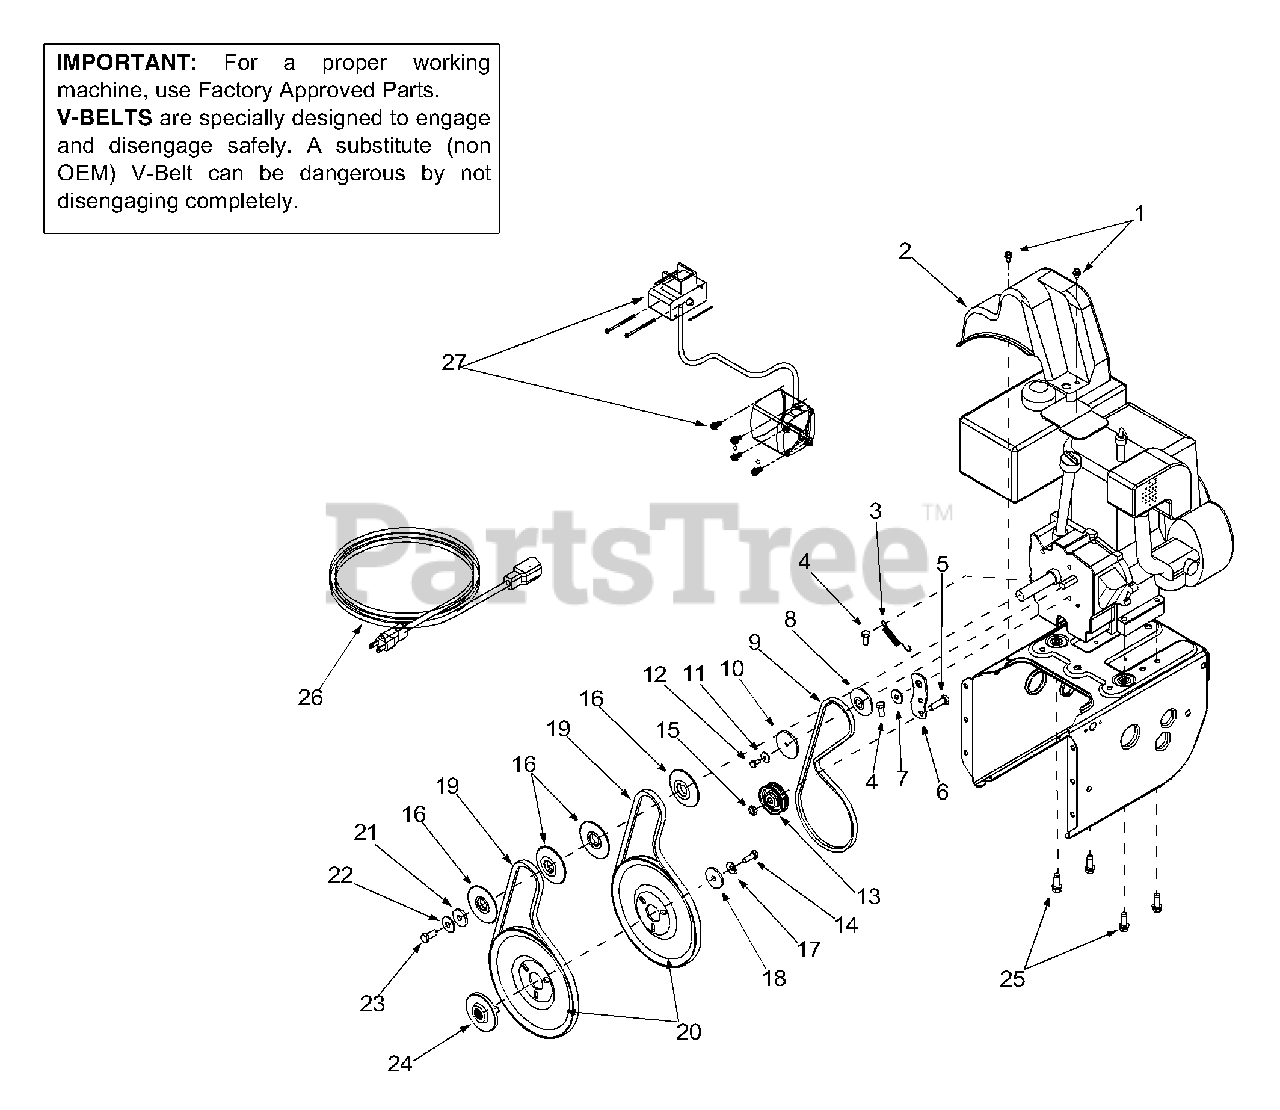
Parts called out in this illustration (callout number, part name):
1	Hex Washer Screw 1/4-20 x .50
2	Belt Cover
3	Extension Spring
4	Hex Screw 5/16-24 x .75
5	Hex Cap Screw 3/8-16 x 1.25
8	Pulley Half
9	V-Belt
10	Pulley Half
11	Bell Washer
12	Hex Cap Screw 1/4-28 x .50
13	Flat Idler
14	Lock Hex Cap Screw 5/16-24
15	Lock Jam Nut 3/8-16
16	Pulley Half
17	Bell Washer
18	Flat Washer
19	Belt
20	Auger Pulley
21	Flat Washer 3/8 x 1.25 OD
22	Bell Washer
23	Hex Cap Screw 3/8-24
24	Adapter Pulley
25	Hex Screw 3/8-16 x 1.0
26	Extension Cord
27	Electric Start
